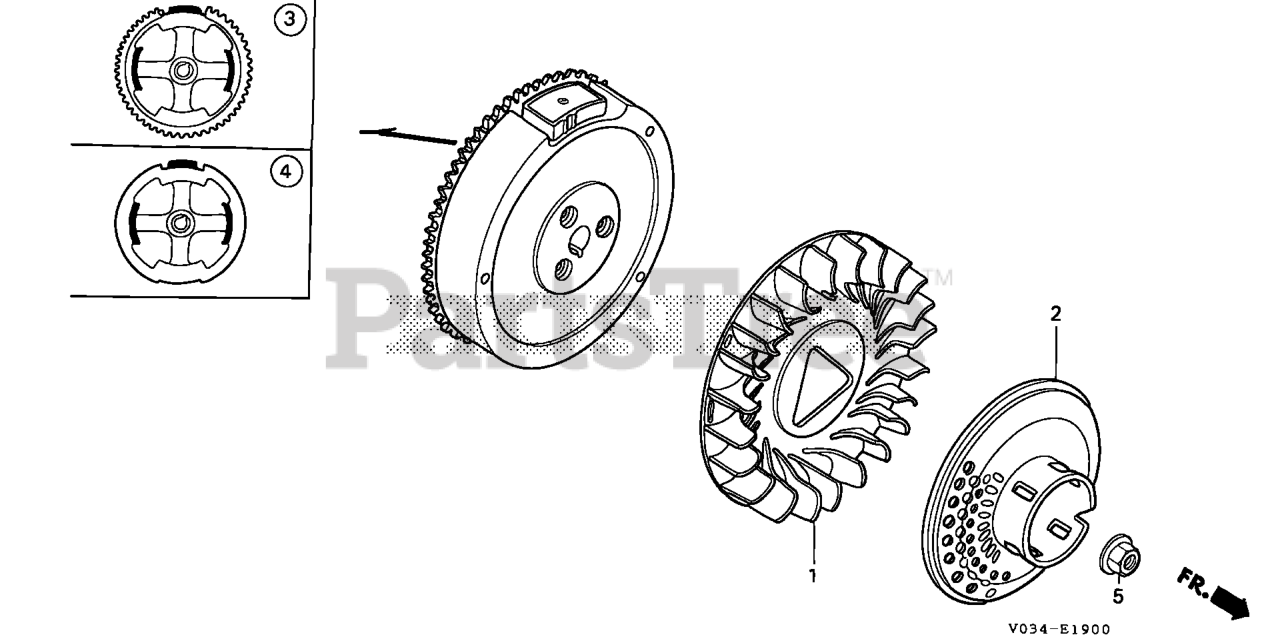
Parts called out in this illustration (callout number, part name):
1	FAN, COOLING
2	PULLEY, STARTER
3	FLYWHEEL (SEL-LAMP)
5	NUT, SPECIAL (16MM)
